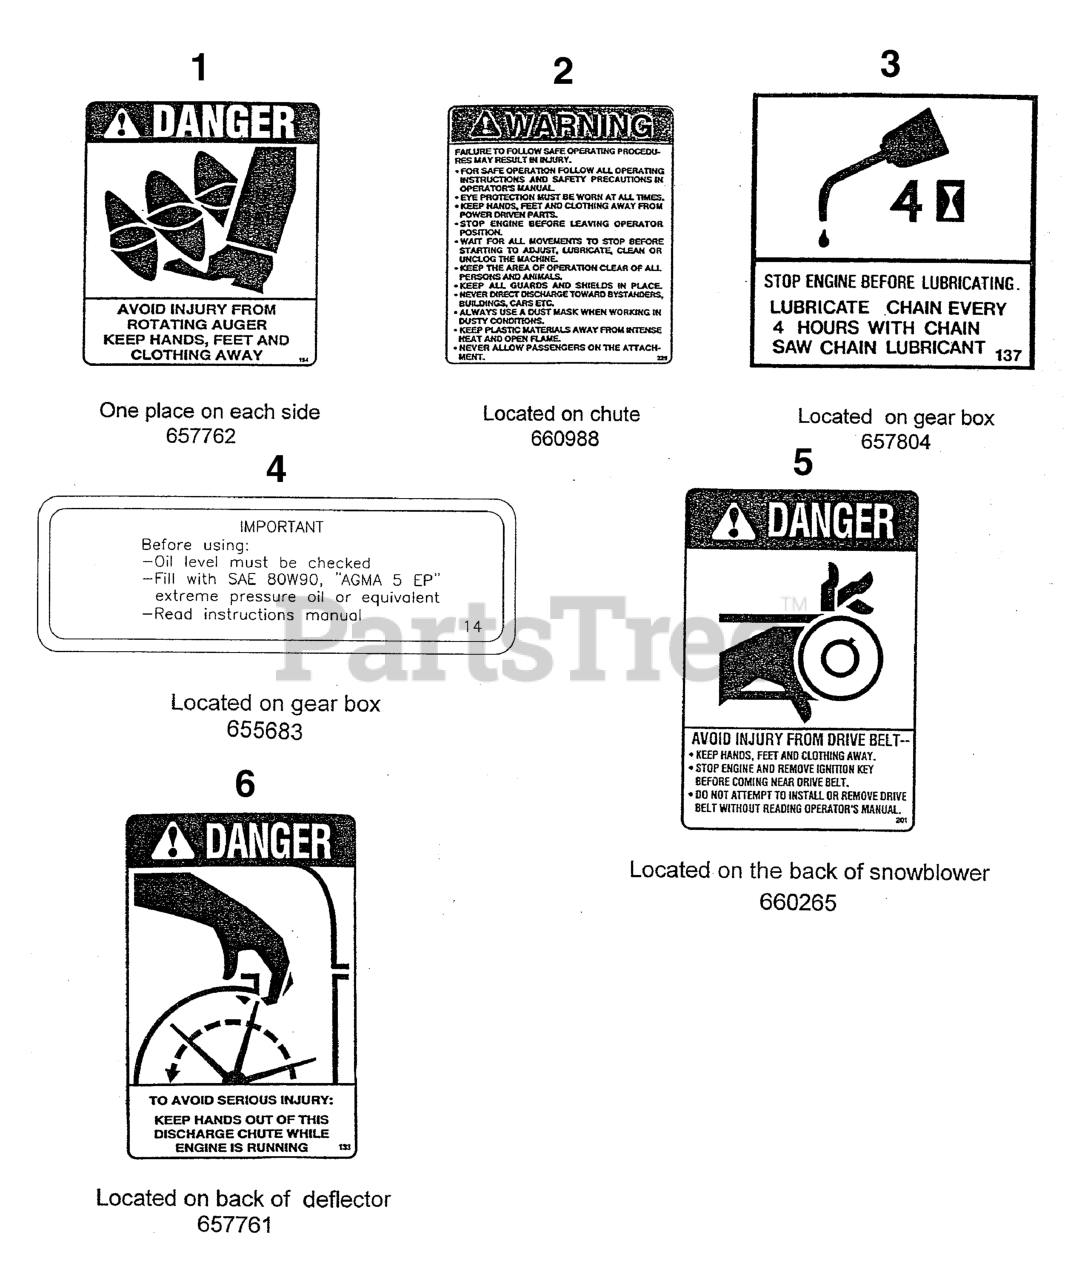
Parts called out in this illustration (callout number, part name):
1	DECAL, DANGER Rotating Auger
2	DECAL, WARNING Operating Procedures
3	DECAL, Lubrication Instructions
4	DECAL, Important Gearbox Lubrication
5	DECAL, DANGER Drive Belt
6	DECAL, DANGER Discharge Chute
